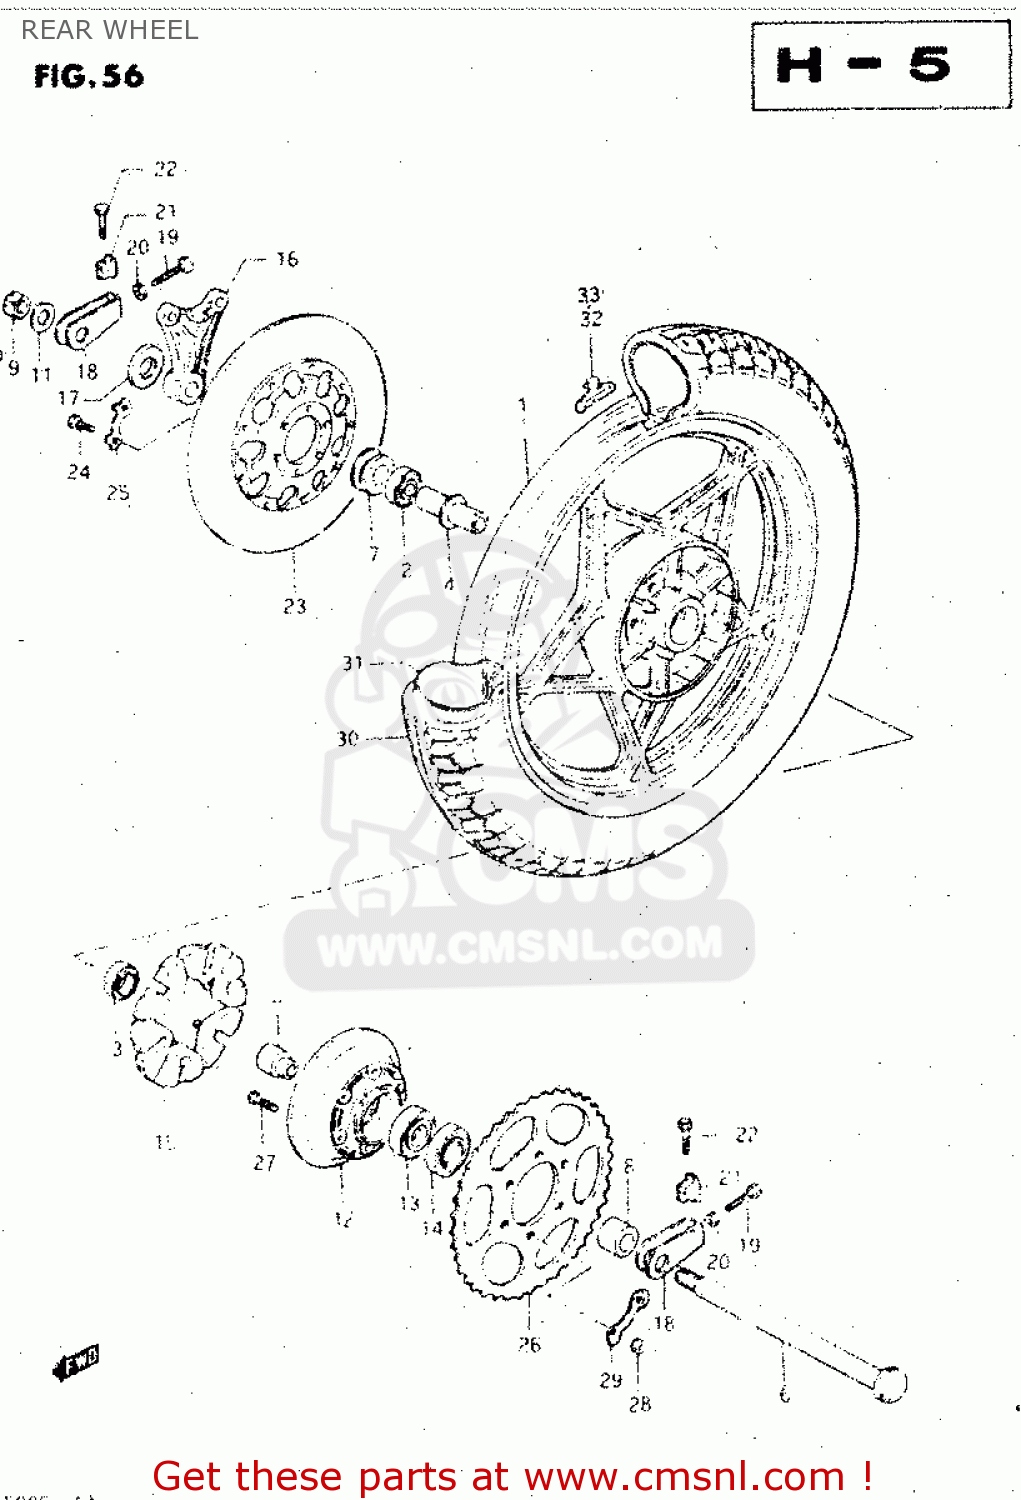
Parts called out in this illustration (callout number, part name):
1	CASTING WHEEL,REAR 2.15
2	BEARING
3	BEARING
4	SPACER,REAR HUB BEARING
5	RETAINER,REAR SPROCKET D
6	AXLE,REAR
7	SPACER,REAR AXLE
8	SPACER (17X33X21.1)
9	NUT
10	PIN,COTTER
11	WASHER (17X30X3.2)
12	DRUM,REAR SPROCKET MOUNT
13	BEARING
14	SEAL,OIL(33X62X7)
15	ABSORBER,REAR HUB SHOCK
16	BRACKET,RR,CALIPER
17	SPACER,REAR CARIPER BRACKET
18	ADJUSTER,CHAIN
19	BOLT
20	NUT
21	SUPPORTER,CHAIN ADJUST
22	BOLT
23	DISC,BRAKE
24	BOLT(8X30)
25	WASHER
26	SPROCKET,REAR (NT:49)
27	BOLT
28	NUT
29	WASHER
30	TIRE
31	TUBE ASSEMBLY,WHEEL,INNER
32	BALANCER,WHEEL
33	BALANCER,WHEEL
